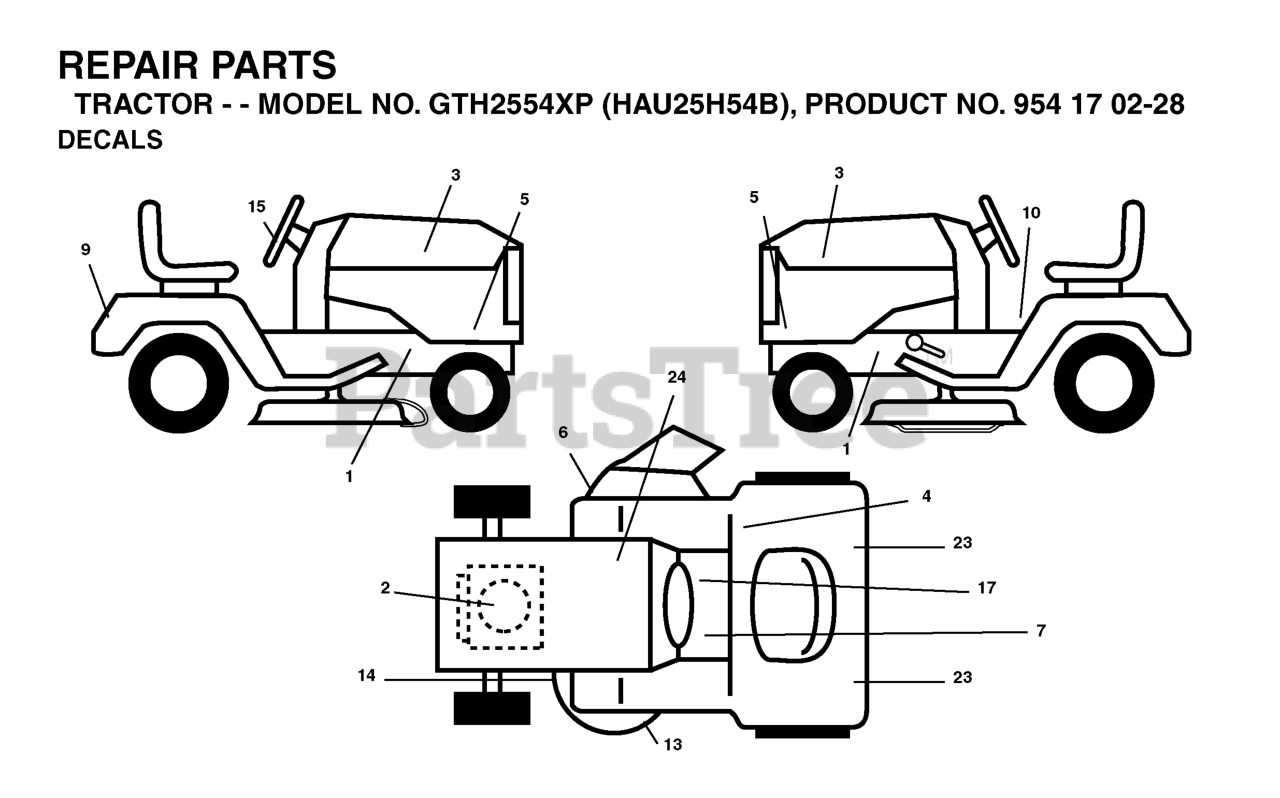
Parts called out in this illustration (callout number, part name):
3	DECAL.HOOD.HUSQVARNA.INTERNATI
4	DECAL
6	DECAL.INTERNATIONL.CUTFINGER
7	DECAL
10	DECAL READ OWNER'S MAN SYMS
13	DECAL.SCHEMATIC.DECK
14	DECAL CLUTCH/BRAKE
15	DECAL.STEERING.HUSQ.BLUE
17	DECAL PARK BRAKE
23	REFLECTOR-TAIL YT
24	DECAL BTRY SYMBOLS
